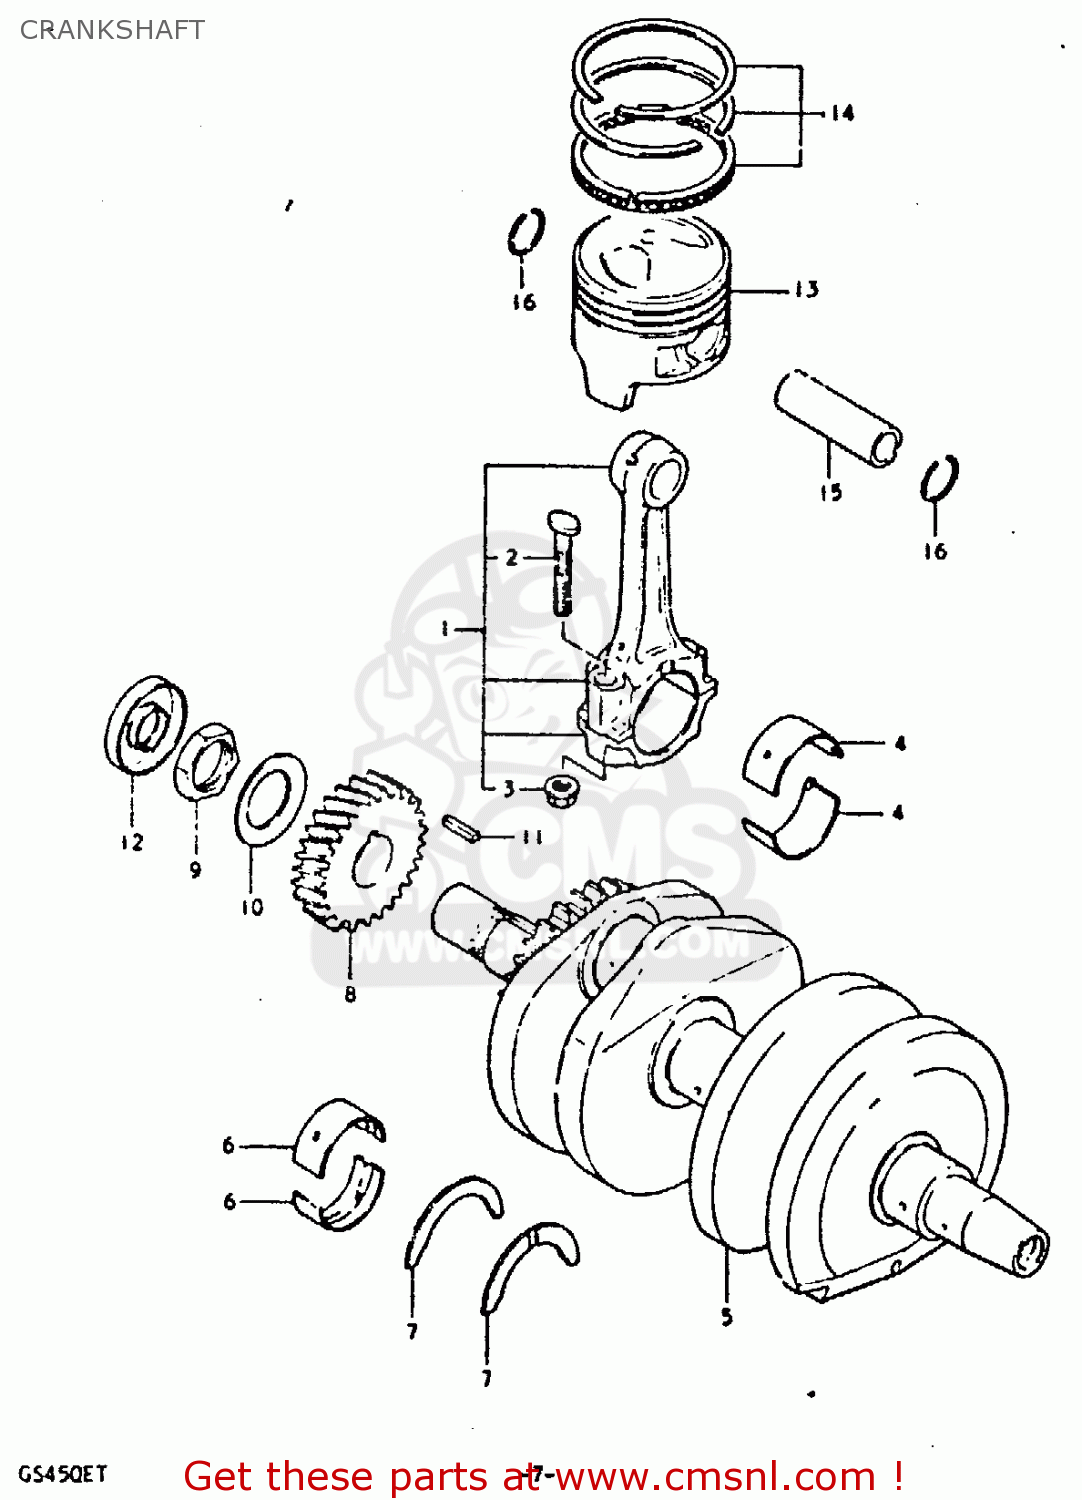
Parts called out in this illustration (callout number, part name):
1	ROD ASSEMBLY,CONNECTING
2	BOLT,CONNECTING ROD
3	NUT
4	BEARING,CRANK PIN
5	CRANKSHAFT
6	METAL CRANKSHAFT
7	PLATE,CRANK THRUST
8	GEAR,PRIMARY DRIVE NO.28
9	NUT
10	WASHER
11	KEY
12	OIL SEAL
13	PISTON
14	RING SET,PISTON
15	PIN,PISTON (18MM)
16	CIRCLIP,PISTON PIN
